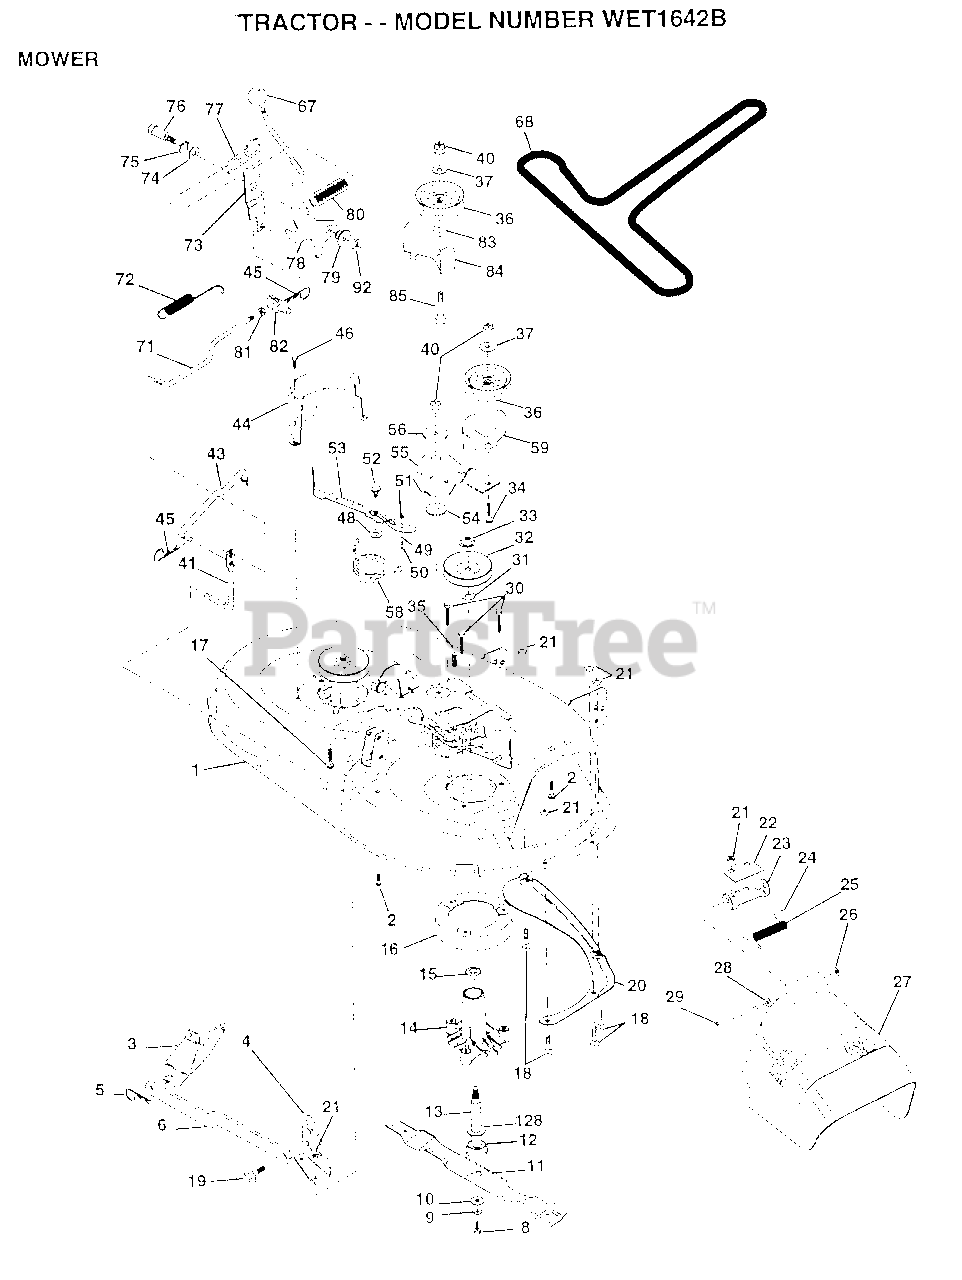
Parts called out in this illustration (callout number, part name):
1	DECK.WELD.42.
2	BOLT
3	BRKT ASM SWAY BAR
4	BRKT DECK SW BAR
8	BLADE BOLT
10	WASHER.HARD.BLADE
11	"BLADE.42"" HIPERF"
12	BEARING.BALL
14	HSG ASM MANDREL
15	BEARING
16	STRIPPER RND MWR
17	BOLT RDHD 3/8-16
18	BOLT
19	BOLT SHD 5/16-18
22	STIFFENER BRKT
23	DEFLECTOR BRKT
24	CAP-SLEEVE LT
25	SPRING TORSION
26	NUT PUSH M
27	DEFLECTOR.SHIELD
28	WASHER
29	HINGE ROD
31	WASHER
32	PULLEY.MANDREL.42
34	BOLT
35	XMAS TREE FASTNER
36	FLAT IDLER PULLEY
37	WASHER
41	PIVOT ROD
43	ROD CLUTCH W/NIBS
44	GUARD MAND LH BLK
45	RETAINER M
46	SCREW.1/4-20X5/8
48	HARD SMALL WASHER
50	SHOULDER BOLT
51	LOCKNUT
52	BOLT.SHLD.5/16-18
53	BRAKE PAD ARM ASM
54	HARDENED WASHER
56	SPACER RETAINER
58	SPRING TORSN BRAK
59	GUARD IDLER TUV
67	KNOB T(3/8 HOLE)
68	BELT.V.T-PATH
71	ROD CLUTCH 38/42
72	RETURN SPRING
73	CLUTCH ARM SECOND
74	WASHER
75	RING
76	SHOULDER BOLT
77	SPRING KEEPER
79	BUSHING
80	SPRING.CLUTCH.MWR
81	NUT
82	TRUNION ADJ
83	WASHER
85	BOLT RDHD 3/8-16
92	NUT
128	WASHER.FELT.
